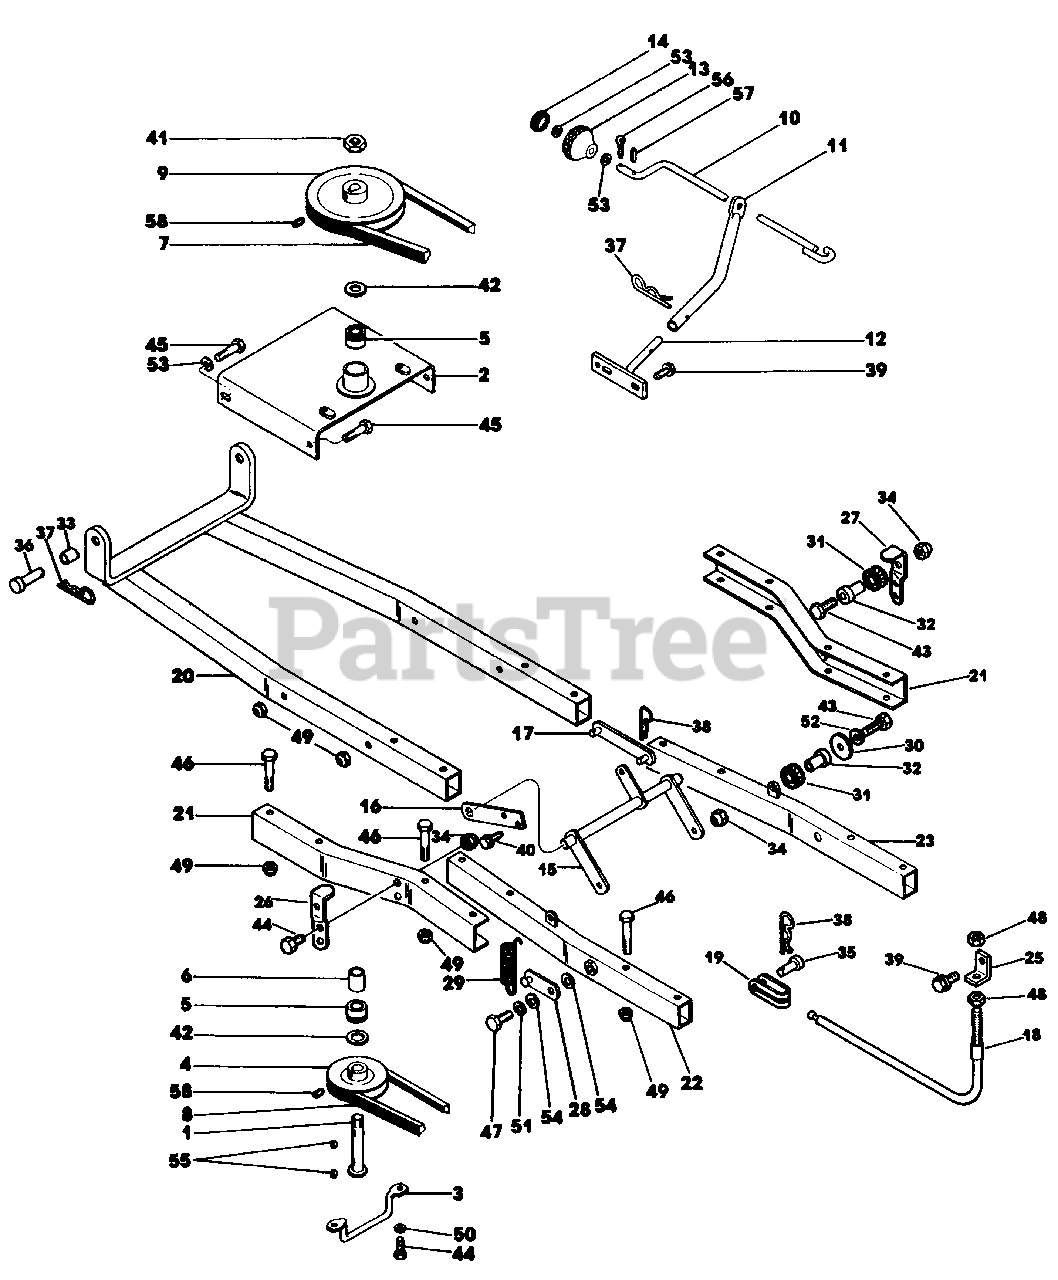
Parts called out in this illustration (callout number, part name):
1	Shaft Assembly
2	Pulley Support Assembly
3	Belt Guard
4	Pulley
5	Bearing w/Snap Ring
6	Spacer
7	V-Belt (Primary)
8	V-Belt (Secondary)
9	Pulley
10	Chute Control Assembly
11	Tube-Chute Control Support
12	Chute Control Support Assembly
13	Knob
14	Plug Bottom & Decal Assembly
15	Bellcrank Assembly
16	Lift Support Arm
17	Lift Link Assembly
18	Lift Cable
19	Cable Clevis
20	Rear Frame Assembly
21	Channel-Frame Connector
22	Front Frame Assembly-R.H.
23	Front Frame Assembly-L.H.
25	Cable Adjustment Bracket
26	Roller Mounting Plate-R.H.
27	Roller Mounting Plate-L.H.
28	Spring Adjustment Arm Assembly
29	Spring Assist
30	Washer
31	Cable Roller
32	Spacer-Roller
33	Space-Gear Drive Tractor Only
34	Nut, Hex Cone Lock 5/16-18 Plated
35	Clevis Pin
36	Clevis Pin
37	Spring Clip
38	Spring Clip
39	Thread Forming Screw, Hex Hd. 5/16-18 x 3/4
40	Thread Forming Screw, Hex Hd. 5/16-18 x 1
41	Nut, Hex Center Lock 5/8-18
42	Thrust Washer
43	Cap Screw, Hex Hd. 5/16-18 x 1-1/2 Plated, Grade 5
44	Cap Screw, Hex Hd. 5/16-18 x 3/4 Plated, Grade 5
45	Cap Screw, Hex Hd. 3/8-16 x 2 Plated, Grade 5
46	Cap Screw, Hex Hd. 3/8-16 x 2-3/4 Plated, Grade 5
47	Cap Screw, Hex Hd. 1/2-13 x 1" Plated, Grade 5
48	Nut, Hex Hd. 5/16-18 Plated
49	Nut, Hex Cone Lock 3/8-16 Plated
50	Washer, Spring Lock 5/16 Plated
51	Washer, Spring Lock 1/2 Plated
52	Washer, Flat 5/16 Plated
53	Washer, Flat SAE 3/8 Plated
54	Washer, Flat SAE 1/2 Plated
55	Key, Woodruff 3/16 x 5/8 Grade 5
56	Pin, Cotter 1/8 x 3/4 Plated
57	Pin, Roll 1/8 x 3/4 Plated
58	Set Screw, Hex Socket Hd. Cup Pt. 5/16-18 x 5/16
